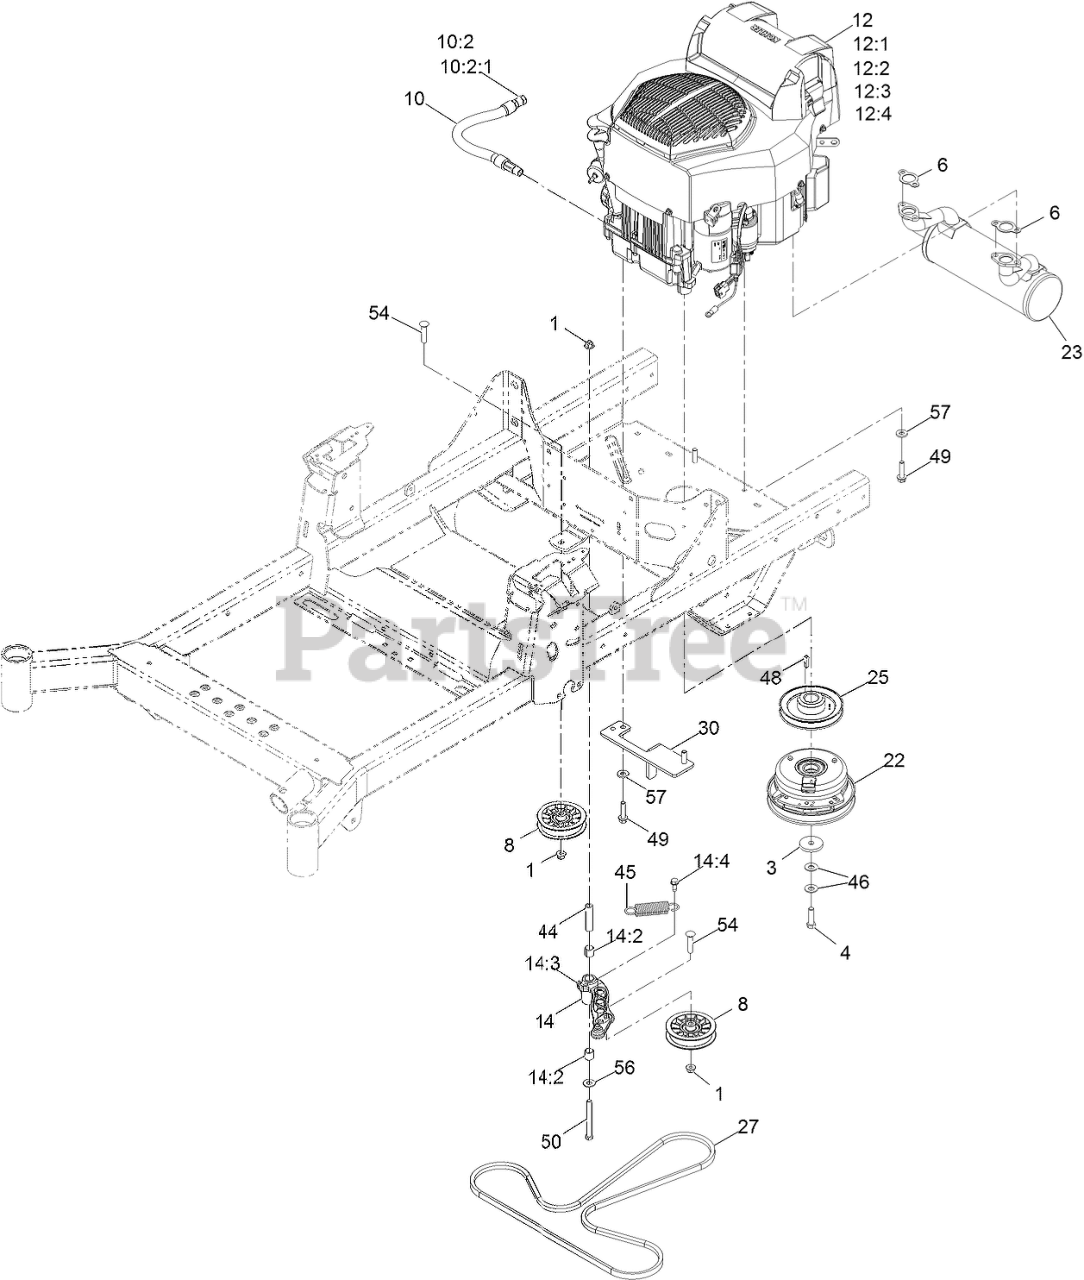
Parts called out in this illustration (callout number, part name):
1	NUT-HF, NI
3	WASHER-CLUTCH
4	SCREW-HH 7/16-20 X 1 1/2 W/LOCTITE
6	GASKET (KOHLER)
8	PULLEY-FLAT IDLER
10	OIL DRAIN HOSE ASM
10:2	PLUG-HH
10:2:1	O-RING
12:1	Kohler 16 083 01-S Engine Air Filter
12:2	Kohler 25 050 44-S Engine Oil Filter
12:3	Kohler 24 050 13-S Fuel Filter
12:4	Kohler 25 083 04-S Safety Filter
14	IDLER ARM ASM
14:2	SLEEVE-BEARING
14:3	FITTING-GREASE, 90 DEG
14:4	SCREW-THD ROLL, HWH
23	MUFFLER-KOHLER AES
25	SHEAVE (W/HUB)
27	BELT-V
30	ANCHOR-CLUTCH
44	BUSHING-PIVOT, IDLER
45	SPRING-EXTENSION
46	WASHER-SPRING
49	SCREW-HWH
50	SCREW-HH
54	SCREW-CARR
56	WASHER-FLAT
57	WASHER-BELLEVILLE
